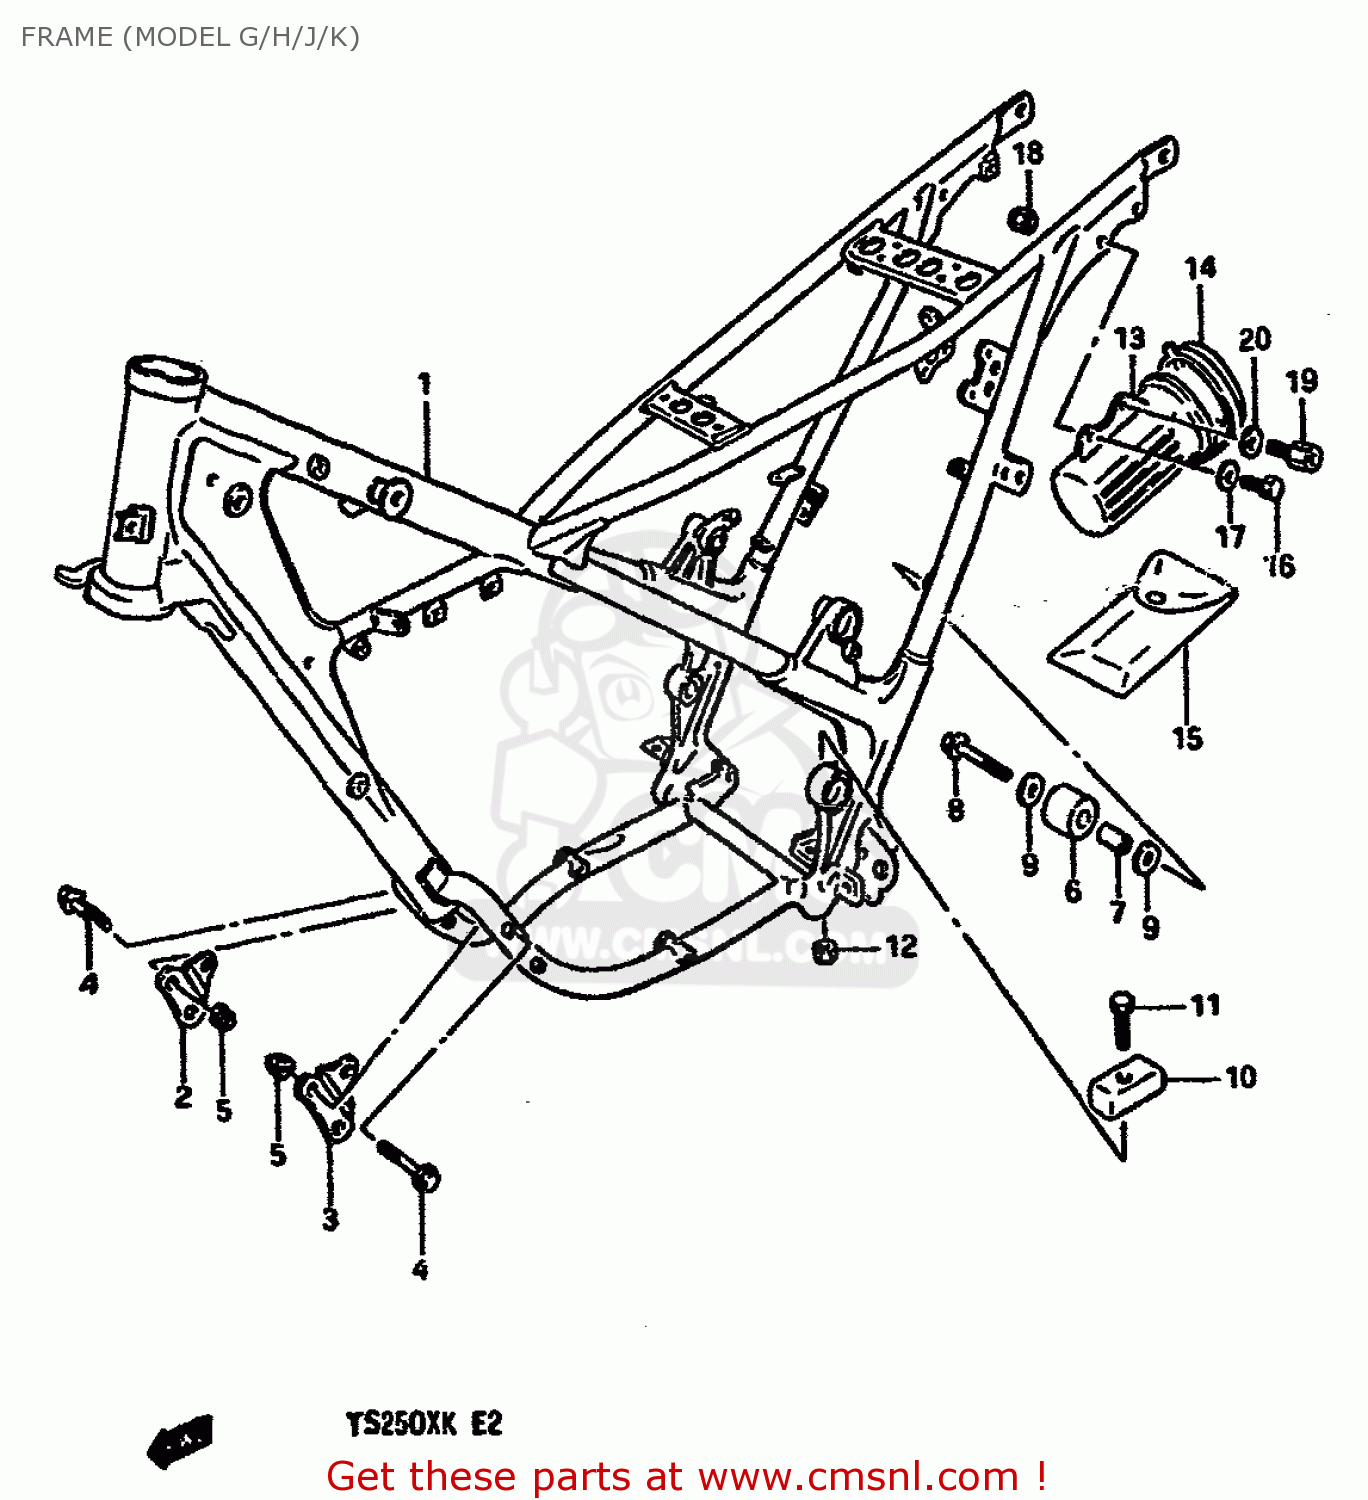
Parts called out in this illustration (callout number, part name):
1	FRAME (BLUE)
2	PLATE,MOUNT RH (SILVER)
3	PLATE,MOUNT LH (SILVER)
4	BOLT
5	NUT
6	ROLLER,CHAIN LENGTH CONTROL
7	SPACER,CHAIN LENGTH ROLLER
8	BOLT(8X45)
9	WASHER
10	GUIDE,CHAIN CONTROL
11	BOLT(6X20)
12	NUT
13	HOLDER,TOOL
14	CAP,TOOL HOLDER
15	TOOL ASSY
16	BOLT
17	WASHER (6.5X18X1.6)
18	NUT
19	BOLT,TOOL HOLDER REAR
20	WASHER (6.5X18X1.6)
